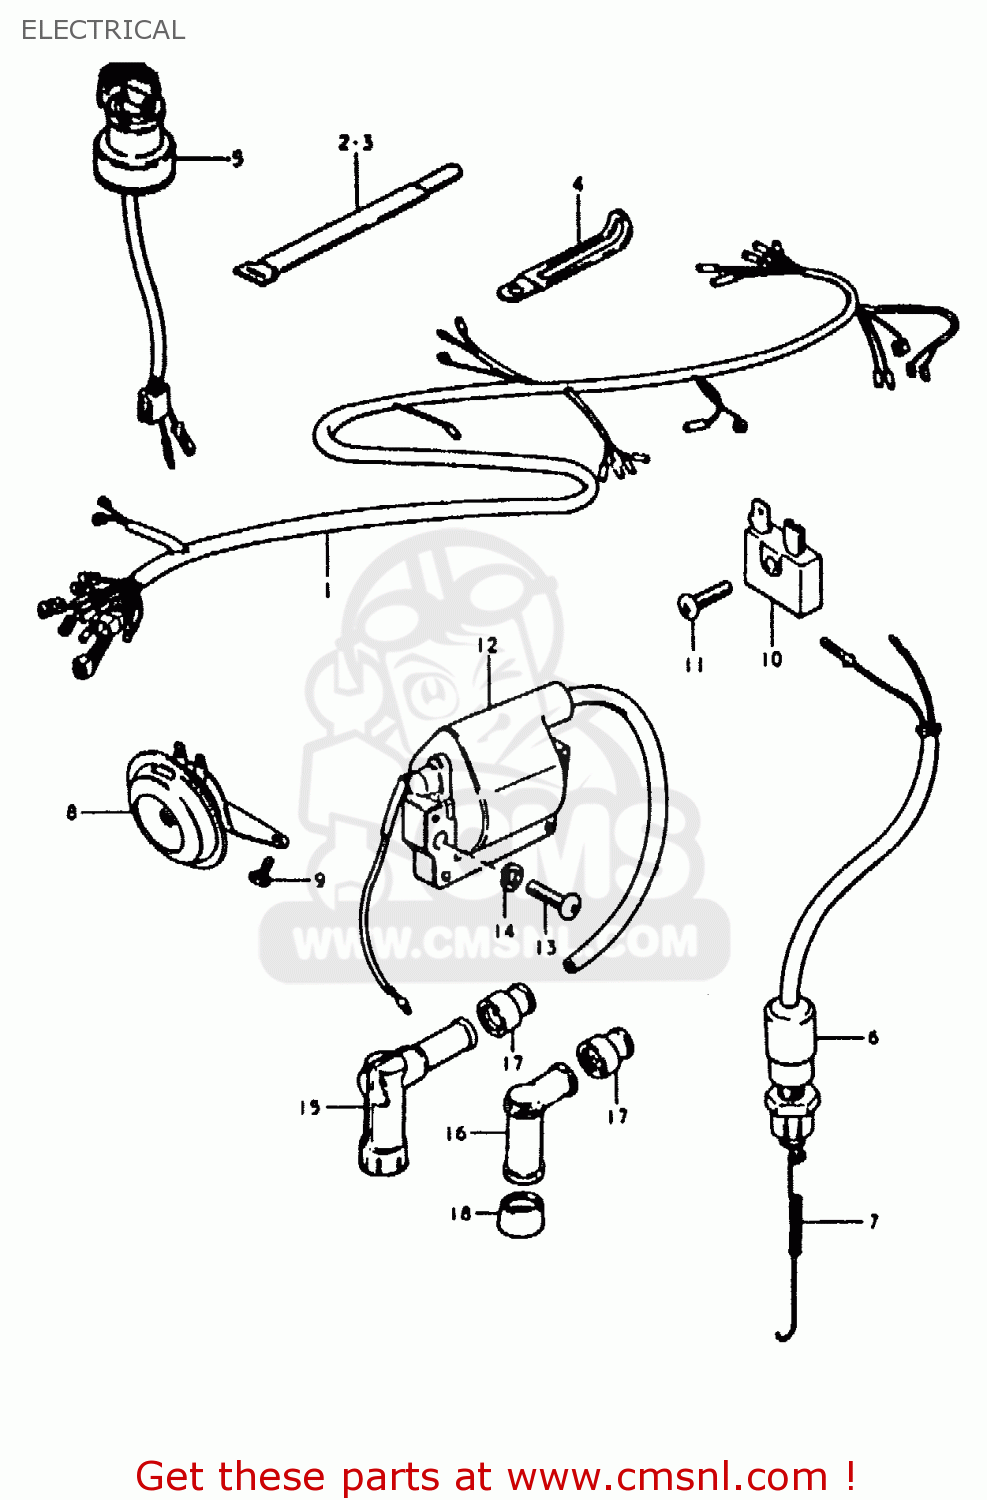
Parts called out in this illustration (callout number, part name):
1	WIRING HARNESS
2	CLAMP
3	CLAMP
4	CLAMP
5	SWITCH, IGNITION
6	SWITCH ASSEMBLY,STOP LAMP
7	SPRING
8	HORN ASSEMBLY
9	BOLT
10	RECTIFIER ASSEMBLY
11	SCREW
12	COIL ASSEMBLY,IGNITION
13	SCREW
14	LOCK WASHER
15	CAP,SPARK PLUG
17	SEAL,SPARK PLU
